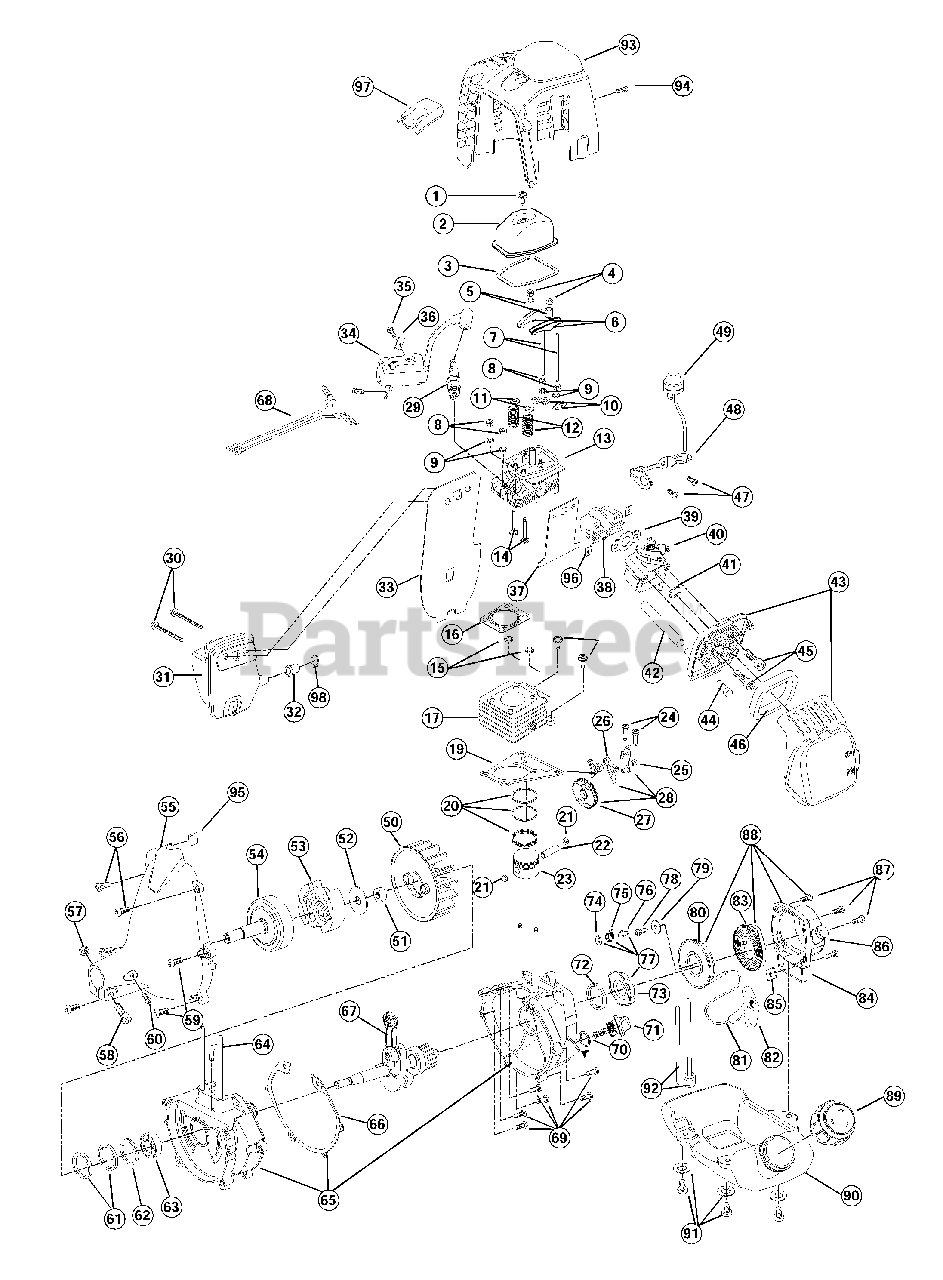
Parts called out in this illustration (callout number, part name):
1	Valve Cover Screw
2	Valve Cover
3	Valve Cover Gasket
4	Rocker Adjustment Nut
5	Rocker Arm Pivot
7	Push Rod
8	Hex Nut
10	Push Rod Guide
11	Valve Spring Retainer
12	Valve Spring
13	Cylinder Head w/Valve Seal (includes 10-14)
16	Cylinder Head Gasket
18	Screw (M5 x 18.7mm)
19	Cylinder Gasket
20	Piston Ring Set (3 Piece Oil Ring)
21	Wrist Pin Button
23	Piston (3 Piece Oil Ring)
24	Cam Bracket Screw
25	Cam Bracket
26	Cam Follower (Chromed)
27	Cam Gear
28	Cam Bracket Assembly (includes 24-27)
29	Spark Plug
30	Muffler Mounting Screw
32	Spark Arrestor Screen
33	Muffler Gasket
34	Module
36	Ground Tab
37	Insulator Gasket
39	Carburetor Gasket
40	Carburetor
41	O-Ring, Carburetor
42	Breather Hose
43	Air Cleaner Assembly
44	Breather assembly
46	Air Filter
48	Throttle Cable Bracket
49	Primer and Line Assembly
52	Clutch Washer
54	Clutch Drum
55	Clutch Housing
56	Screw
58	Engine Bolt
59	Screw
60	Anti-Rotation Screw
61	Oil Seal
65	Crankcase (includes 66 & 69)
66	Crankcase Gasket
67	Crankshaft
68	Lead Wire
70	O-Ring
71	Oil Cap Dipstick (includes 70)
72	Oil Seal
73	Pulley with Nut
74	Retaining Ring
76	Ratchet
77	Pulley Assembly (includes 73-76)
80	Recoil Pulley
82	Pull Handle
83	Recoil Spring
84	Recoil Case
85	Square Nut
88	Recoil Case Assembly (includes 78-87)
90	Fuel Tank
91	Screw with Washer
92	Fuel Line Assembly
93	Engine Cover
95	Wire Grommet
97	Spark Plug Cover
98	Spark Arrestor Clamp
